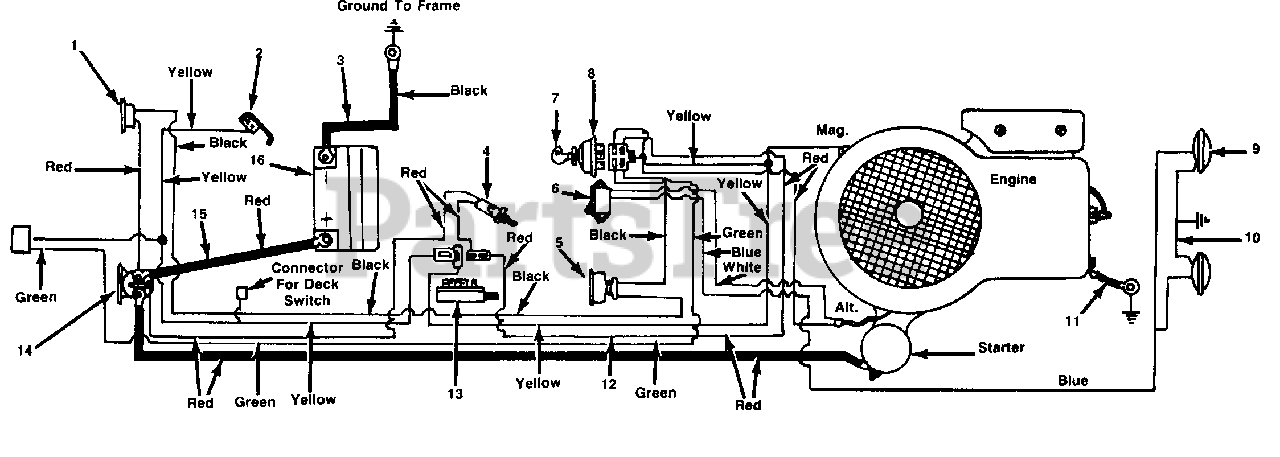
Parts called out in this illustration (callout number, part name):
1	Circuit Breaker
2	Spring Switch
3	Ground Wire 9.0" Lg.
4	Safety Switch
5	Ammeter
6	Light Switch
7	Ignition Key
8	Ignition Switch
9	Headlight
10	Grounding Wire
11	Ground Wire 7.25" Lg.
12	Wire Harness
13	Safety Switch
14	Solenoid
15	Electric Wire
16	12V Battery
